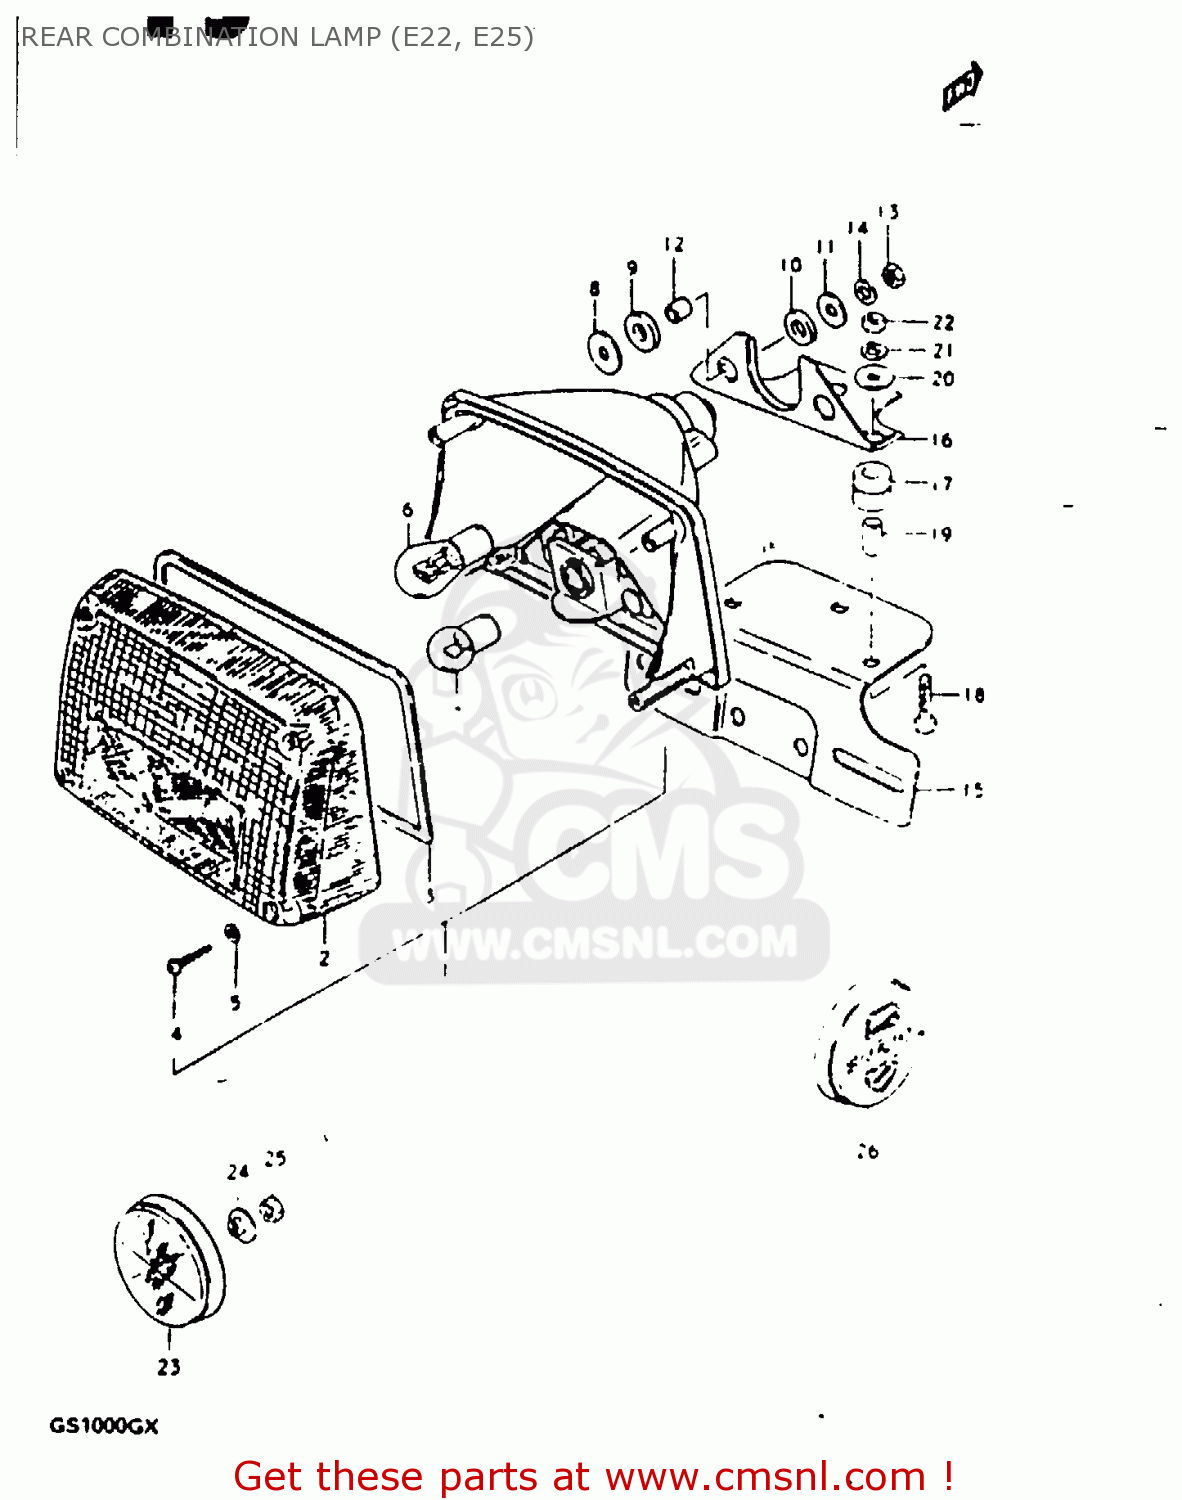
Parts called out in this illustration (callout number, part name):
1	LAMP, REAR COMBINATION
2	LENS
3	GASKET (NAS)
4	BOLT
5	GASKET (NAS)
6	BULB(12V21/5W)
7	BULB(12V10W,TOKAI DENSO)
8	WASHER
9	CUSHION
10	CUSHION
11	WASHER(6,5X22X1.6)
12	SPACER(6.1X9X7.5)
13	NUT
14	LOCK WASHER
15	BRACKET, LICENCE PLATE
16	BRACKET,LICENSE PLATE
17	CUSHION, BRACKET
18	BOLT
19	SPACER (6.4X9X15.5)
20	WASHER
21	LOCK WASHER
22	NUT
23	REFLEX REFLECTOR,RR
24	SPACER
25	NUT
26	EMBLEM, REAR SIDE
